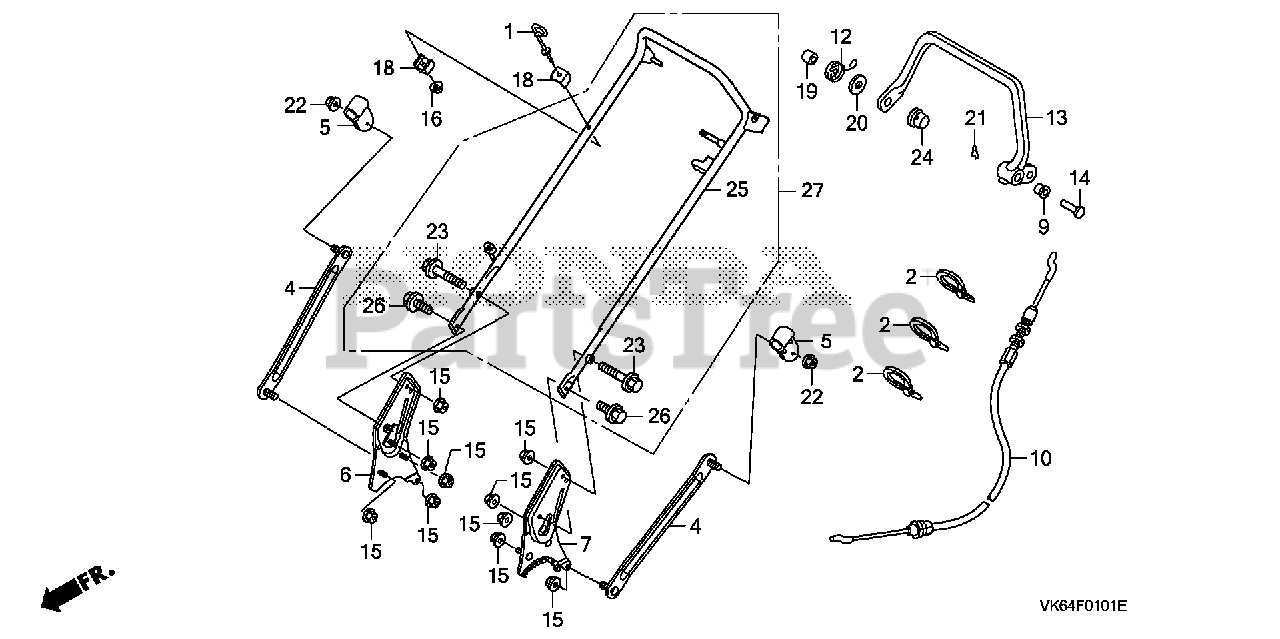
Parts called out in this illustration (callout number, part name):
1	GUIDE, ROPE
2	TIE, CABLE
4	PLATE, HANDLE SUPPORT
5	HANGER, HANDLE SUPPORT
6	STAY, R. HANDLE
7	STAY, L. HANDLE
9	BUSH, CLUTCH LEVER
10	CABLE, BRAKE
12	SPRING, R. STOP RETURN
13	LEVER, BRAKE *NH105* (MAT BLACK)
14	PIN, CLUTCH LEVER
15	NUT, SELF-LOCK (8MM)
16	NUT, NYLON LOCK (6MM)
18	WASHER, FRAME JOINT
19	COLLAR (8X11X13.5)
20	WASHER, PLAIN (8MM)
21	PIN, LOCK (8MM)
22	NUT, SELF-LOCK (8MM)
23	BOLT, FLANGE (8X40) Use up to Engine SN 1003236.
24	NUT, PUSH (8MM)
25	PIPE, HANDLE
26	BOLT, FLANGE (8X16) Use from Engine SN 1000016.
26	BOLT, FLANGE (8X40) Use up to Engine SN 1003236.
27	PIPE KIT, HANDLE
